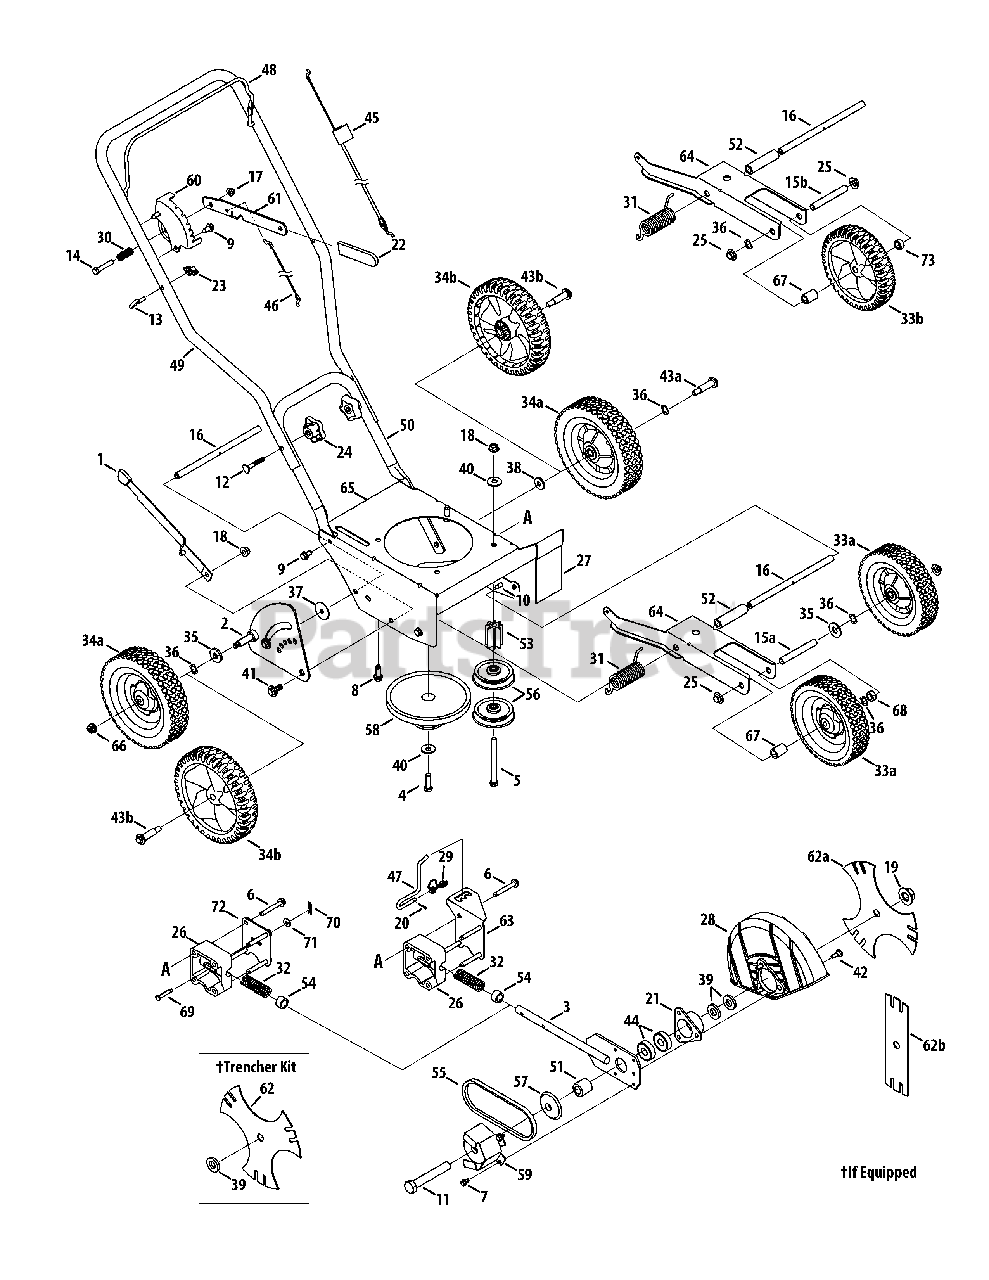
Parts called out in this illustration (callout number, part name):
1	Curb Height Adjustment Lever
2	Curb Height Adjuster Plate
3	Blade Plate Assembly
4	Screw 3/8-24
5	Screw 3/8-16
6	Hex Screw, 5/16-18
7	Self-tapping Screw, 1/4-20
8	Screw, 3/8-16
9	Hex Screw, 5/16-12
10	Hex Screw 5/16-18
11	Hex Screw, 5/8-18
12	Carriage Bolt, 5/16-18
13	Rope Guide (Eye Bolt)
14	Hex Screw, 5/16-18
16	Frame Spacer .50x9.25
17	Lock Flange Nut, 5/16-18
18	Flange Nut 3/8-16
19	Flange Nut, 5/8-18
20	Clevis Pin 3/32 x .625
21	Bearing Cup
23	Wing Nut
24	Star Knob
25	Push Cap 1/2" rod
26	Bearing Block
27	Debris Guard
28	Blade Guard
29	Double Torsion Spring
30	Compression Spring
31	Torsion Spring
32	Compression Spring
35	Flat Washer, .531 x 1.25 x .181
36	Wave Washer .531 x .781 x .013
37	Flat Washer, .385 x 1.5 x .075
38	Flat Washer .385 x 1.0 x .135 †
39	Flat Washer .635x1.24x.181
40	Bell Washer,.396 x 1.140
41	Shoulder Screw, 3/8-16
42	Shoulder Screw
44	Bearing, .625 ID x 1.57 OD
45	Control Cable
46	Wheel Adjustment Cable
47	Blade Adjustment Rod
48	Bail Handle
51	Spacer, .63 x 1.12 x 1.06
52	Spacer
53	Pulley Mount Spacer
54	Spacer, .64 x.88 x .50
56	Flat Idler Pulley, 2.5 OD
57	Sheave
58	Combination Flywheel Pulley
59	Belt Guard
61	Depth Index Lever
63	Bracket Plate
64	Dual Wheel Bracket
65	Frame
66	Flange Lock Nut, 3/8-16
67	Spacer., .525 x .775 x .93
68	Spacer., .505ID x .88OD x .440
69	Clevis Pin, .250 x 1.53
70	Cotter Pin, .072 x 1.12
71	Flat Washer, .283 x .75 x .030
72	Cover Plate
73	Spacer, .525 x .775 x .3125
